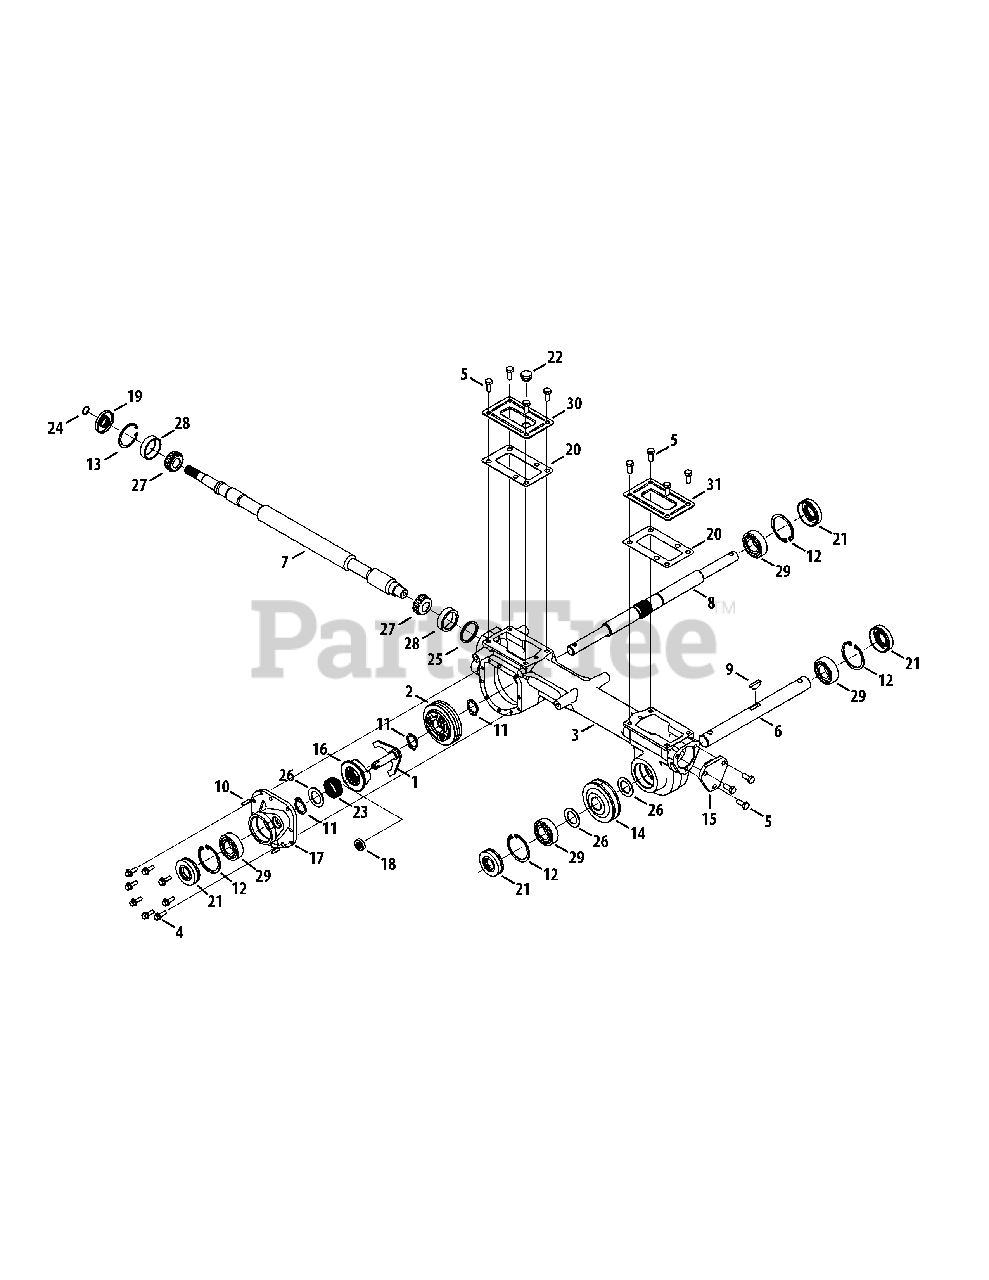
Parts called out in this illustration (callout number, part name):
1	Shift Yoke Assembly
2	Worm Gear Assembly
3	Housing Assembly
4	Hex Head Screw, 1/4-20 x .75
5	Hex Screw, 5/16-18, .75, Gr5
6	Shaft, Tiller
7	Shaft, Worm
8	Axle Shaft
9	Key, Hi Pro .25 x 1.062
10	Dowel Pin
11	Ring, Snap
12	Retaining Ring
13	Retaining Ring, Int
14	Worm Gear, 30t, LH
15	Bearing Cover
16	Disconnect Collor
17	Wheel Cover
19	Seal, Oil, .750 Shaft x 1.783 Bore
20	Gasket, Gear Housing
21	Seal, Oil, 1.00 Shaft x 2.00 Bore
22	Rubber Plug, Oil
23	Spring, 1.5 x 1.14 x .800
24	Wire Ring
25	Washer, Flat, 1.50 x 1.75 x .062
25	Washer, Flat, 1.50 x 1.75 x .005
25	Washer, Flat, 1.50 x 1.75 x .03
25	Washer, Flat, 1.50 x 1.75 x .010
26	Washer, Flat, 1.010 x 1.56 x .060
27	Cone Bearing
28	Bearing Cup
29	Ball Bearing
30	Cover, Transmission
31	Cover, Transmission
